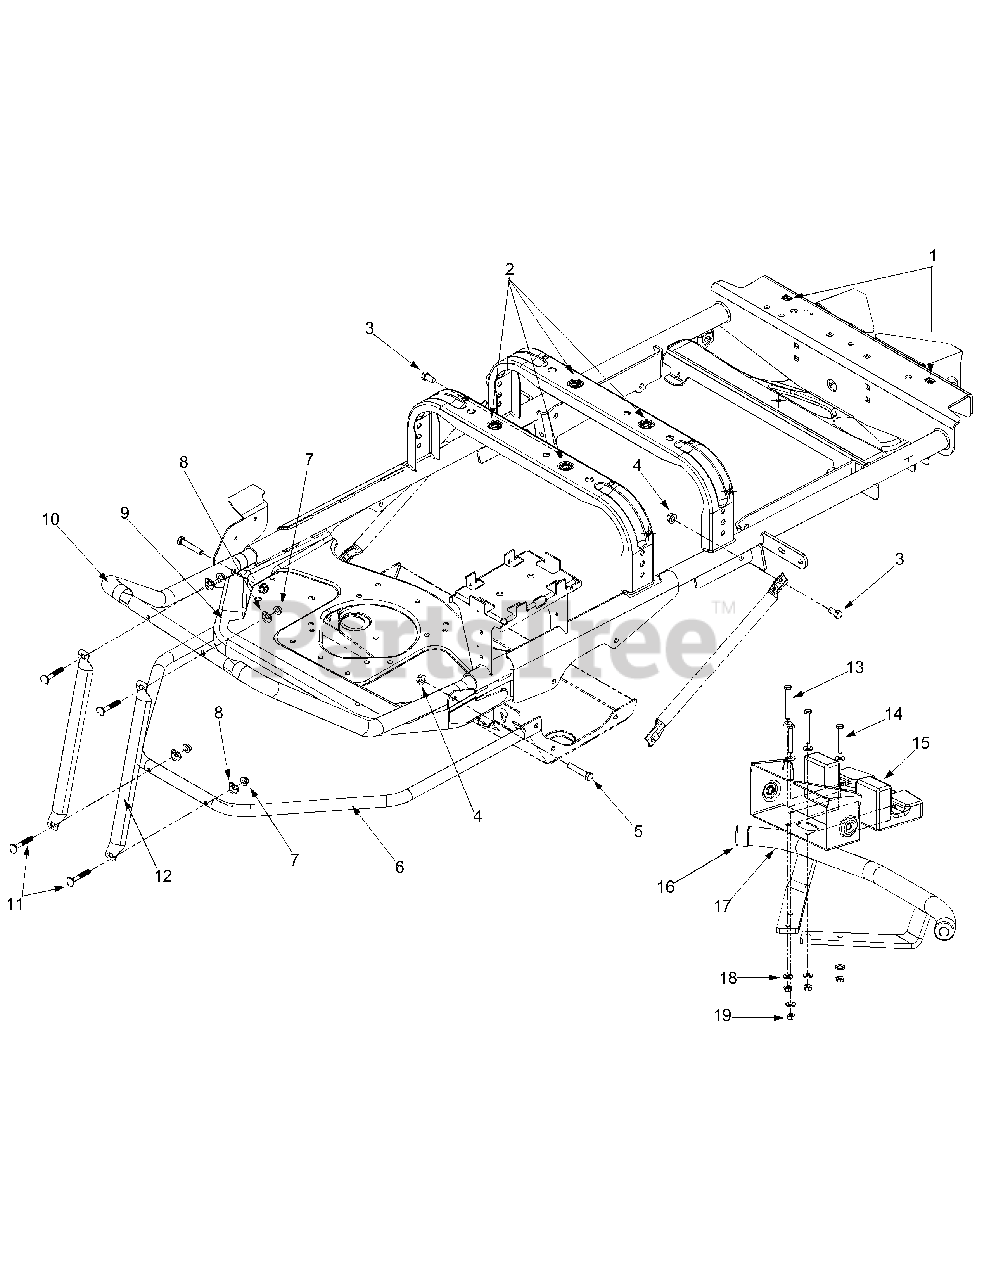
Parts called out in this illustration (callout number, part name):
1	Retainer Nut 3/8-16
2	Retainer Nut 3/8-16
3	Hex Cap Screw 3/8-16 x .75
4	Flange Lock Nut 3/8-16
5	Hex Cap Screw 3/8-16 x 2.0
8	Washer .320 ID x .93 OD
14	Hex Cap Screw 3/8 - 16 x 2.5
19	Flange Lock Nut 3/8-16
